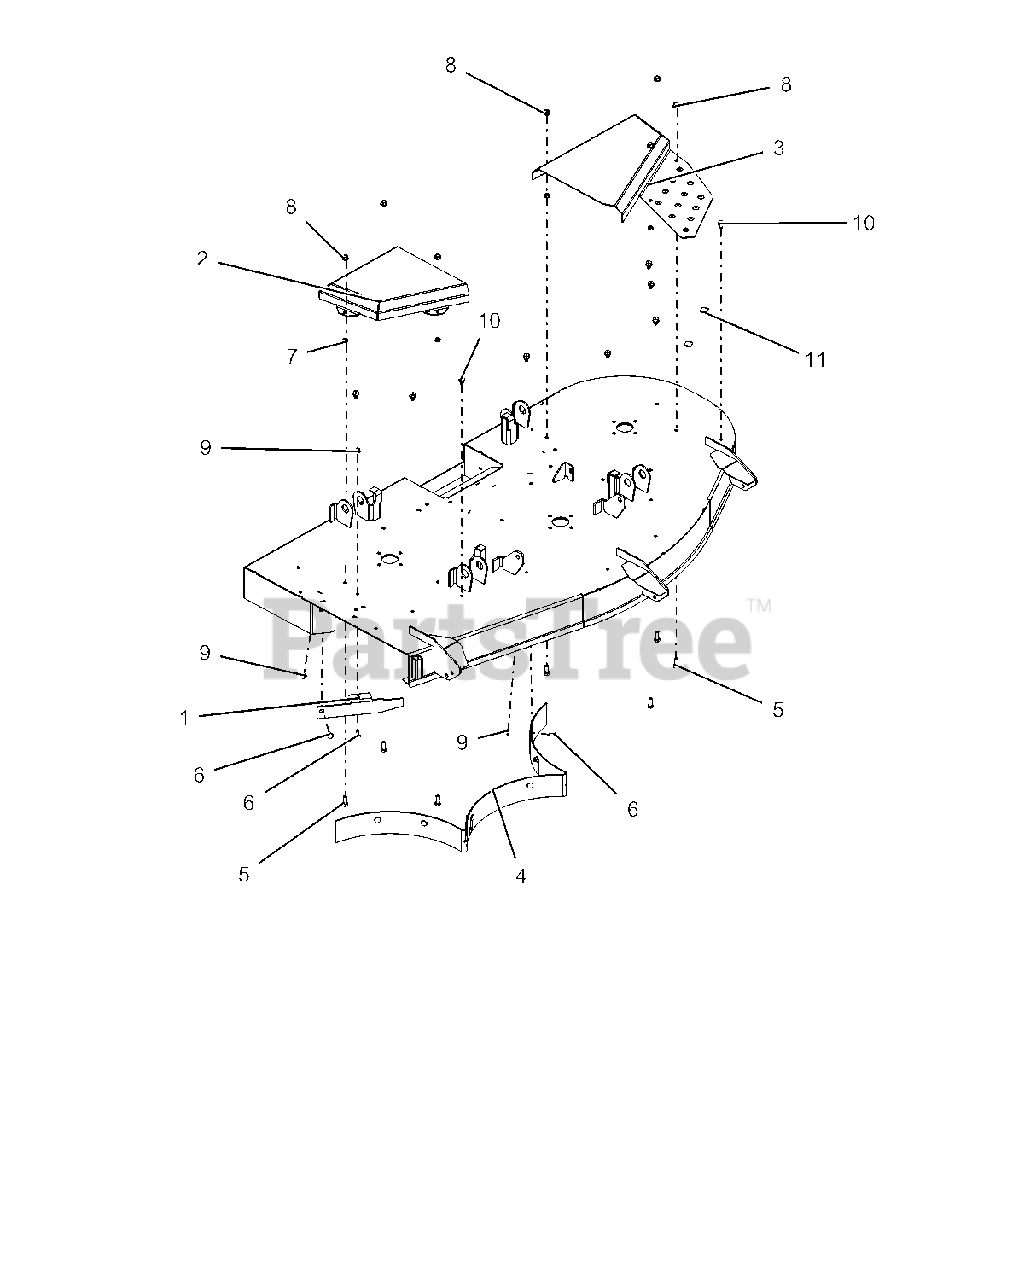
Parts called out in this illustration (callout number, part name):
1	BAFFLE, DISCHARGE - 60" (RED)
2	COVER, RH BELT - 60" (RED)
3	COVER, LH BELT - 60"
4	BAFFLE, REAR BOLT-IN, 60" XL (RED)
5	BLT-HEX .38-16X1.00 GR5 YWZC
6	BLT-RDHDSQNK .31-18X.75 G5 YWZC
7	NUT, JAM .375-16 YWZC
8	NUT, LK-TOP-FLG .38-16 YWZC
9	NUT, LK-TOP-FLG .312-18 YWZC
10	SCR-TAP .38-16X.50 HWH TR YWZ
